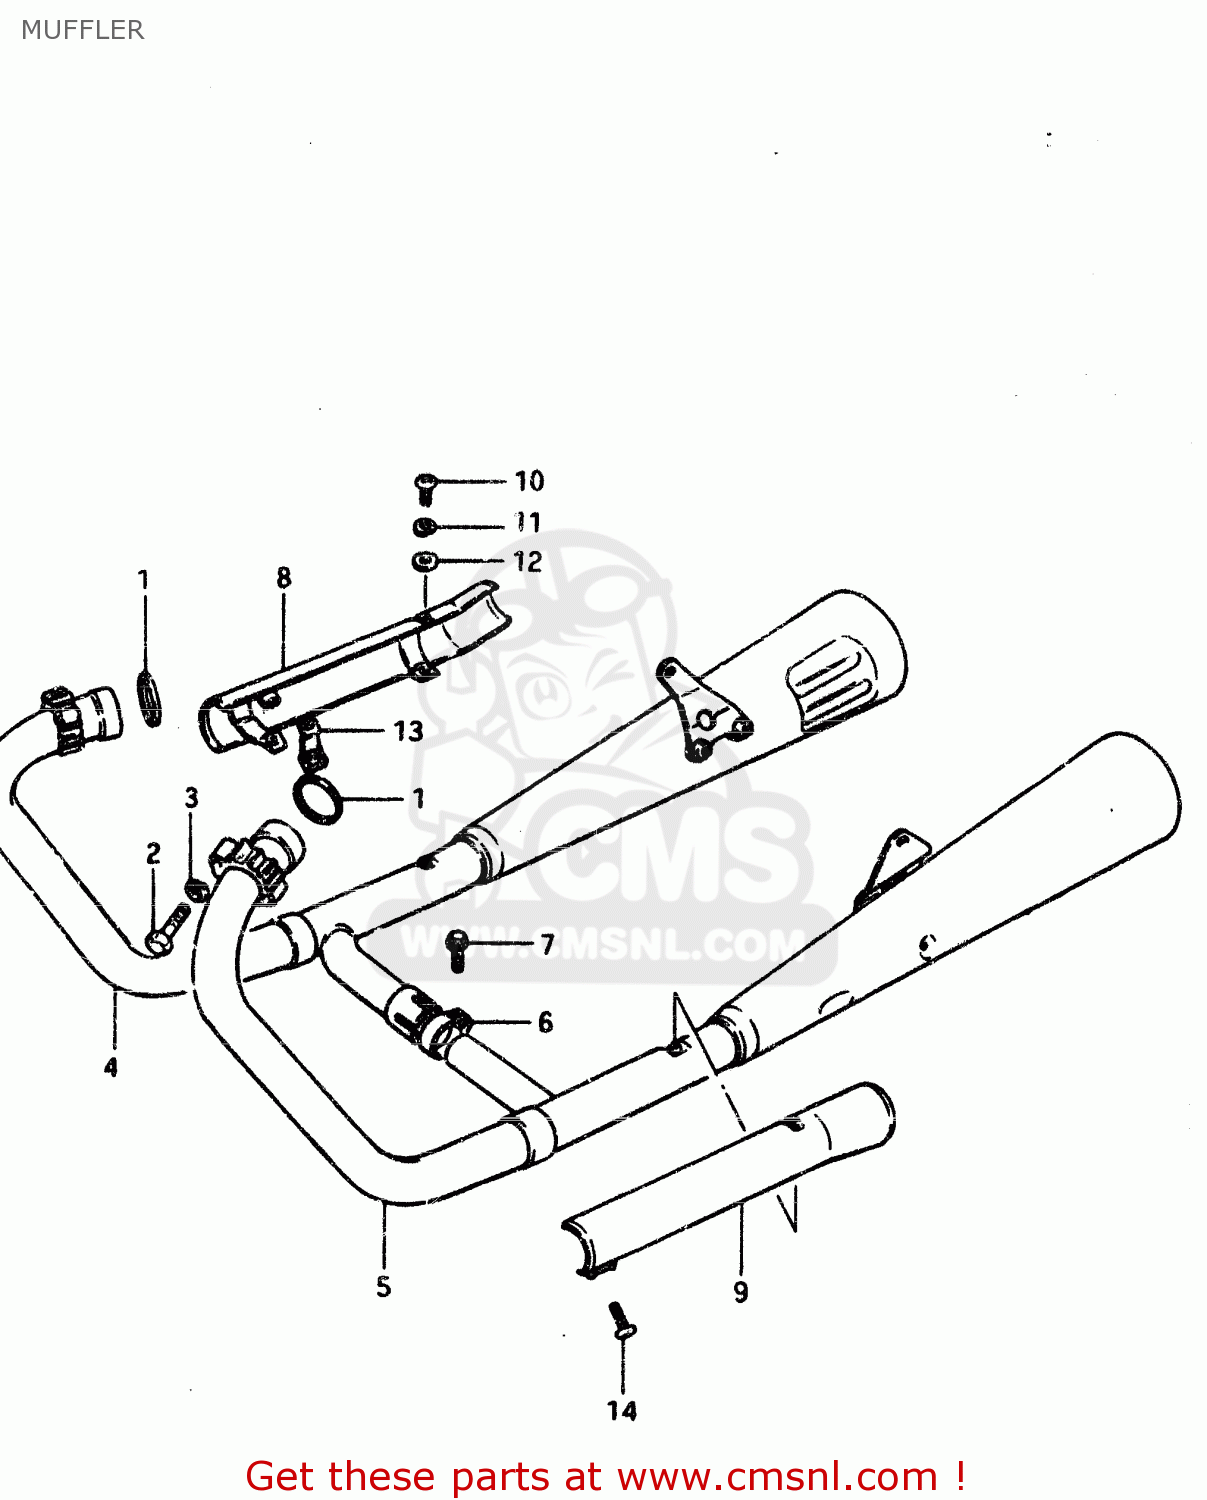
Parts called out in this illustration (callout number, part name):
1	GASKET,EXHAUST PIPE (NAS)
2	BOLT 8X40
3	LOCK WASHER
4	MUFFLER ASSEMBLY
5	MUFFLER ASSEMBLY
6	CLAMP
7	BOLT
8	COVER,MUFFLER,RIGHT
9	COVER,MUFFLER LH
10	SCREW
11	LOCK WASHER
12	WASHER
13	CLAMP,MUFFLER COVER
14	SCREW
